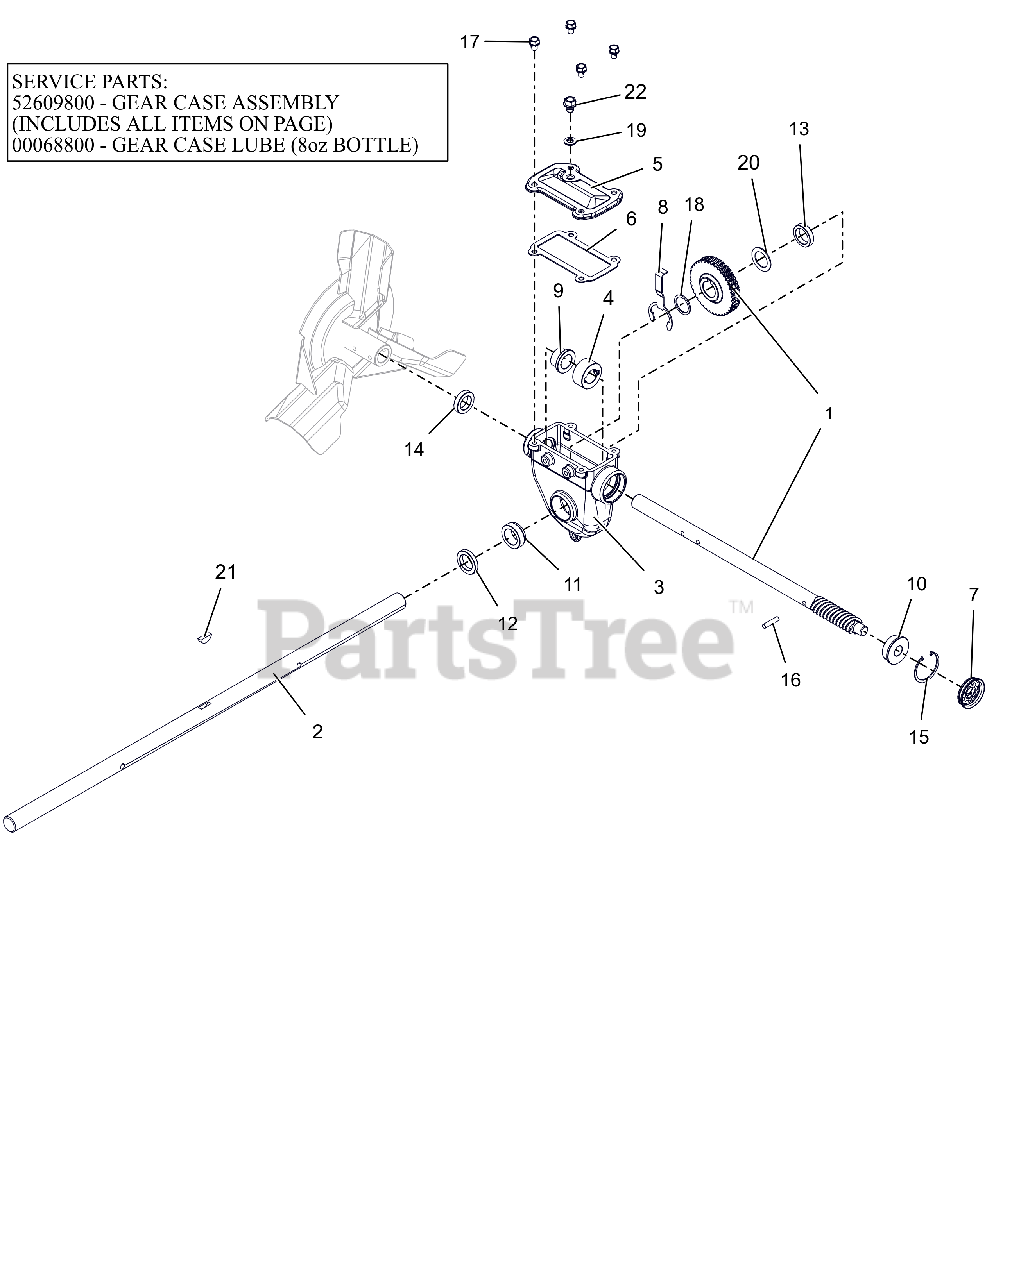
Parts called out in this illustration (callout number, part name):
1	ASSY, WORM SHAFT & GEAR
2	SHAFT, RAKE-32"
3	GEARCASE, LARGE MACHINED
3	GEAR CASE, 32" IRON PRO TOP-LD
3	ARIENS L3 LUBE, 8 OZ BOTTLE
4	THRUST COLLAR, .875"ID SLIPFIT
5	COVER, TOP - LARGE IRON
6	GASKET, TOP - LARGE GEARCASE
7	COVER, GEAR CASE 1.75"
8	BUSHING RETAINER, LARGE
9	BSHG-FLG .879X1.128X.75X1.45
10	BSHG-FLG .628X1.503X.58X1.725
11	BSHG-FLG LARGE, RIGHT
12	SEAL-OIL .999X1.500X.250 TBC29
13	SEAL-OIL .999X1.375X.312 TBC29
14	SEAL-OIL .873X1.375X.312 TBC29
15	RG-RTNG-INT 1.750X.062
16	PIN-STR .250X1.12 6150
17	BOLT, SEMS .31-18X.50 GR5 YWZC
18	WSHR-FL-STL 1.010X1.250X.068YZ
19	WSHR-BND-SEAL .38X.75X.11 GALV
20	WSHR-FL-STL 1.010X1.505X.062YZ
21	KEY-WDRF .25X.875 HRD #A
22	@SCR-ROLOK .38-16X.50 HWH YWZC
